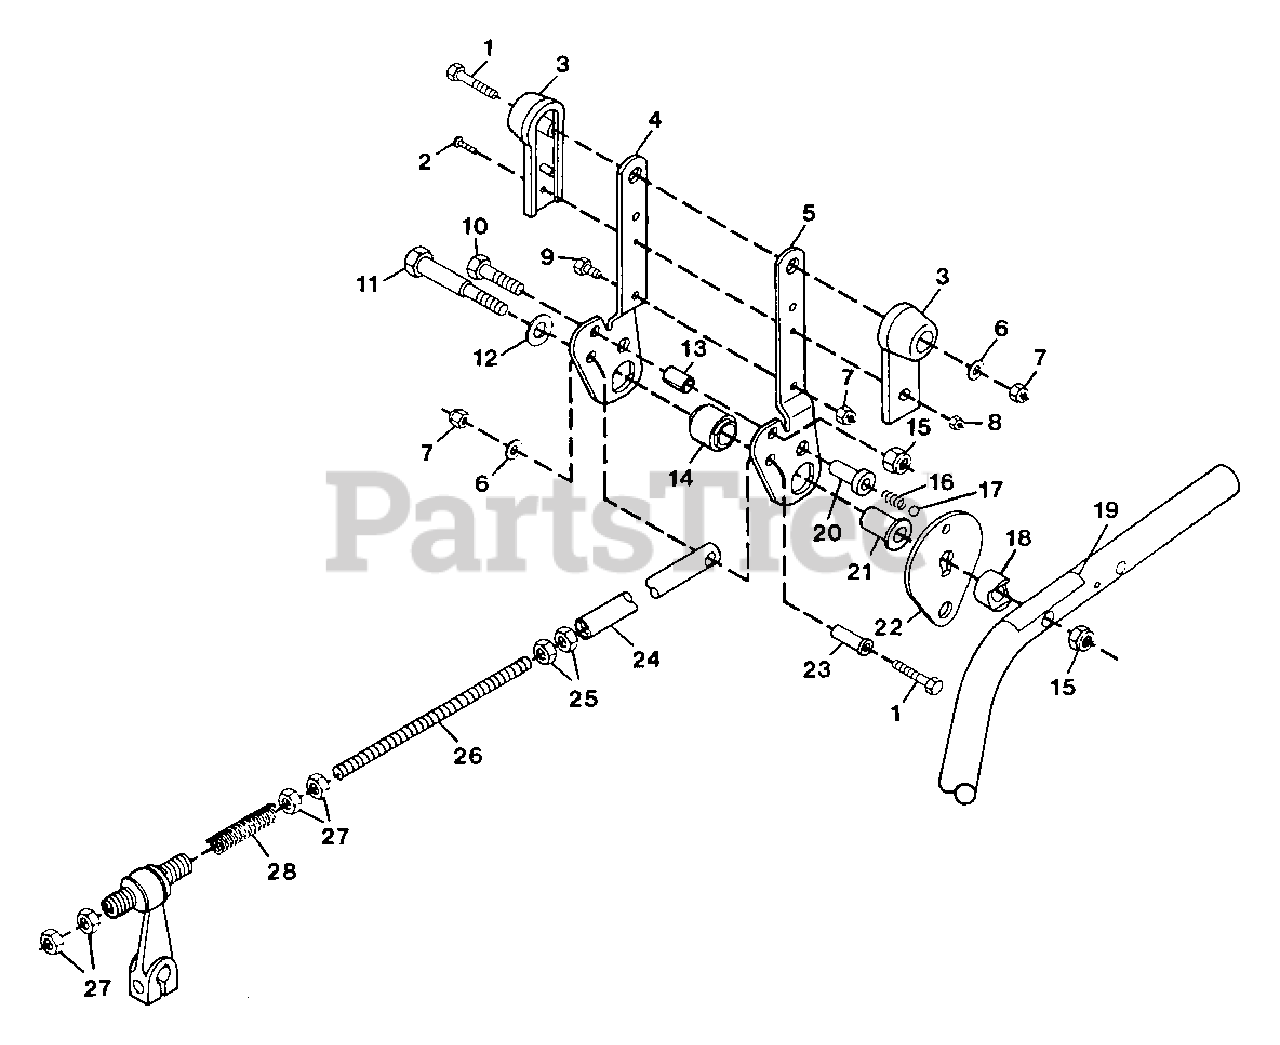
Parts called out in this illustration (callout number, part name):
1	Bolt, Hex 1/4-20x1.50
2	Screw, Machine 6-32x.625 PHD
3	Knob, Handle Control
4	Handle, Control R.H.
5	Handle, Control L.H.
6	Washer, Flat .281x.625x.065
7	Nut, Lock 1/4-20
8	Nut, Lock 6-32
9	Bolt, Hex 1/4-20x.625
10	Bolt, Hex 3/8-16x1.50
11	Bolt, Hex Step
12	Washer, Flat .531x1.062x.095
13	Sleeve, Handle Stop
14	Bushing, Handle
15	Nut, Lock 3/8-16
16	Spring, Comp. 7/8x.28
17	Ball, Steel 5/16
18	Bracket, Handle Pivot
19	Decal, Fwd-Rev French
20	Bushing, Neutral
21	Pivot, Handle
22	Plate, Neutral
23	Bushing, Oper. Presence Handle
24	Rod, Control Fwd-Rev
25	Nut, Hex 3/8-16
26	Rod, Control Extension
27	Nut, Jam 3/8-16 Hex
28	Spring, Fwd-Rev Neutral Return
